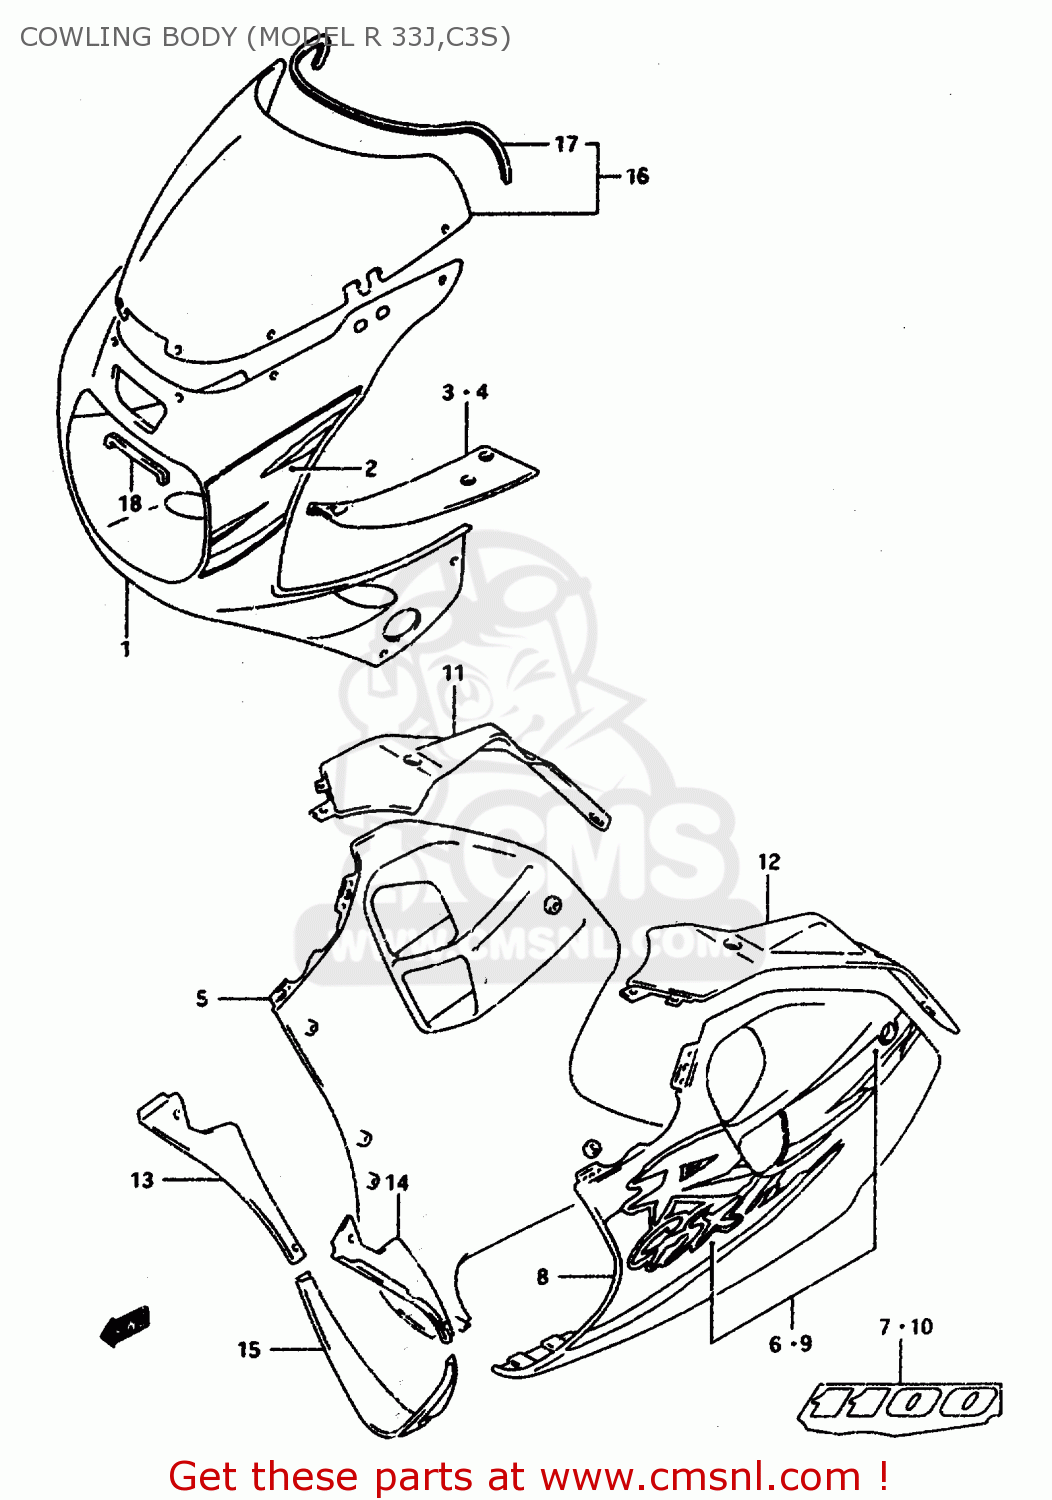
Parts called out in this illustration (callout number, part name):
1	COWLING ASSY,BODY
2	TAPE SET, BODY
3	PANEL,UPR,R
4	PANEL,UPR,L
5	COWLING,UNDER,
6	TAPE SET, UNDER RH
7	EMBLEM, 1100 (GRAY)
8	COWLING ASSY,UNDER,L
9	TAPE SET, UNDER LH
10	EMBLEM, 1100 (GRAY)
11	PANEL,LWR,R
12	PANEL,LWR,L
13	COWLING,UNDER INNER,R
14	COWLING,UNDER INNER,L
15	COWLING,UNDER CTR
16	SCREEN SET,WIND
17	MOLDING,WINDSCREEN
18	COWLING,UNDER CTR
19	SCREEN SET,WIND
20	MOLDING,WINDSCREEN
21	CUSHION,FR POSITION LAMP
